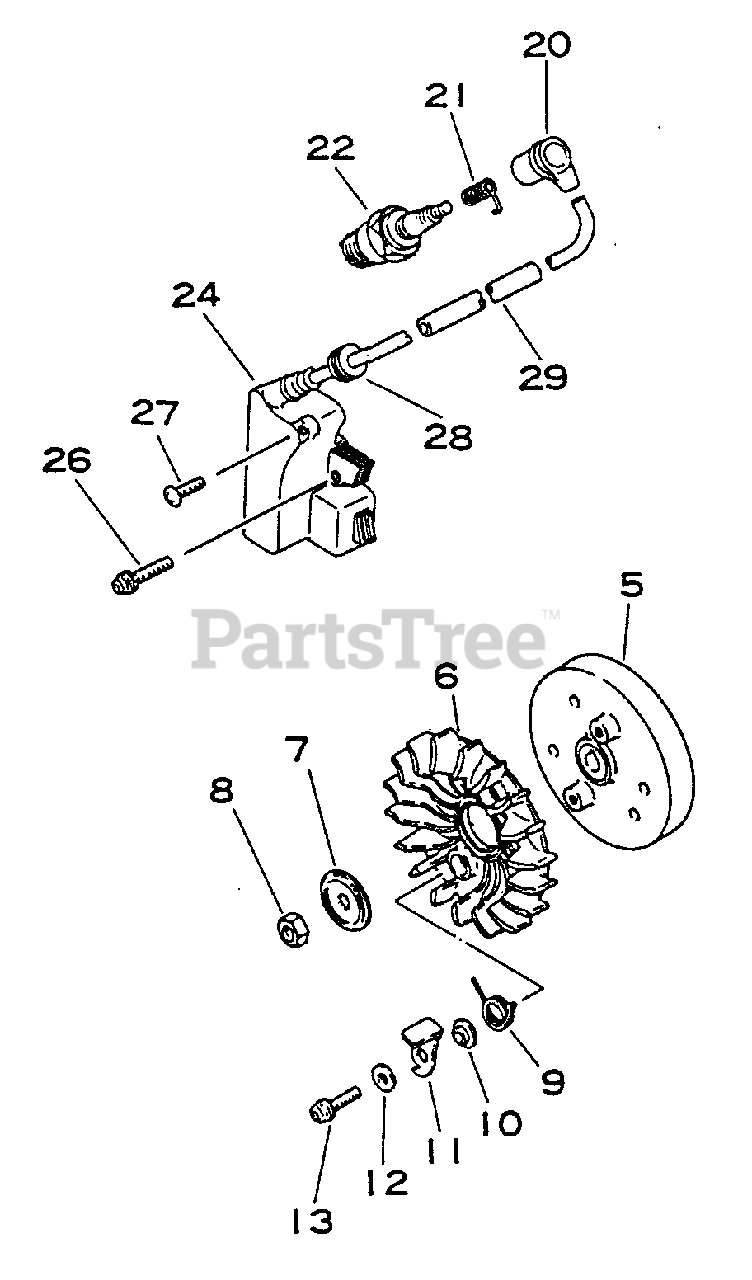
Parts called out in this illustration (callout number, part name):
5	FLYWHEEL
6	FAN
7	WASHER - CUP
9	SPRING, RETURN
11	PAWL, STARTER
12	WASHER - 5
13	SCREW - 5X14
20	CAP, SPARK PLUG
21	TERMINAL, SPARK PLUG CAP
22	SPARK PLUG -- CJ-6Y
24	COIL, IGNITION
26	SCREW - 4X20
27	SCREW - 4X8
